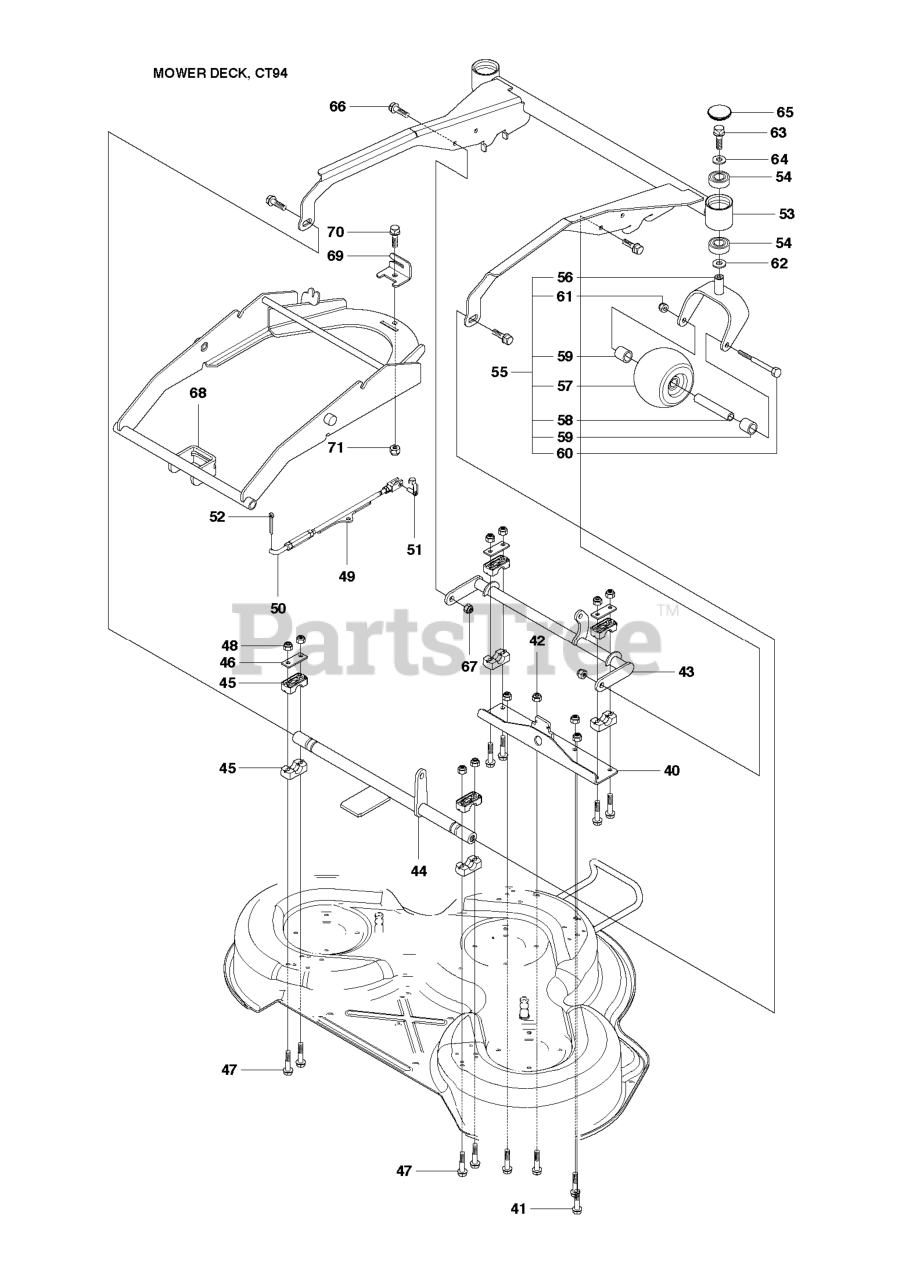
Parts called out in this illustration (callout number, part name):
42	LOCKNUT M8
48	LOCKNUT M8
50	PARALLEL ROD
54	BALL BEARING 6004-2RS1
55	PIVOT WHEELS
57	DECK ROLLER, FRONT
61	NUT
65	HUB CAP PIVOT WHEEL
67	LOCKNUT M8
71	LOCKNUT M8
